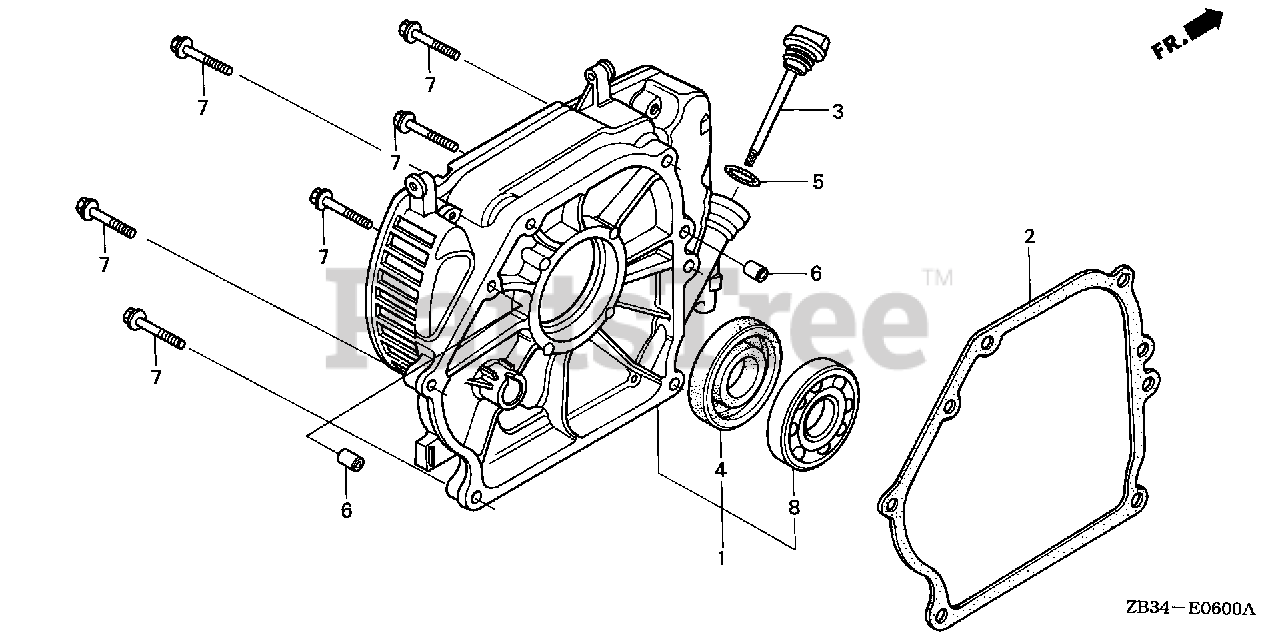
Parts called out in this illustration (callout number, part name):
1	COVER ASSY., CRANKCASE
2	GASKET, CASE COVER
3	CAP, OIL FILLER
4	OIL SEAL (25X41X6)
5	O-RING (16MM)
6	PIN, DOWEL (8X14)
7	BOLT, FLANGE (8X32)
8	BEARING, RADIAL BALL (6205)
